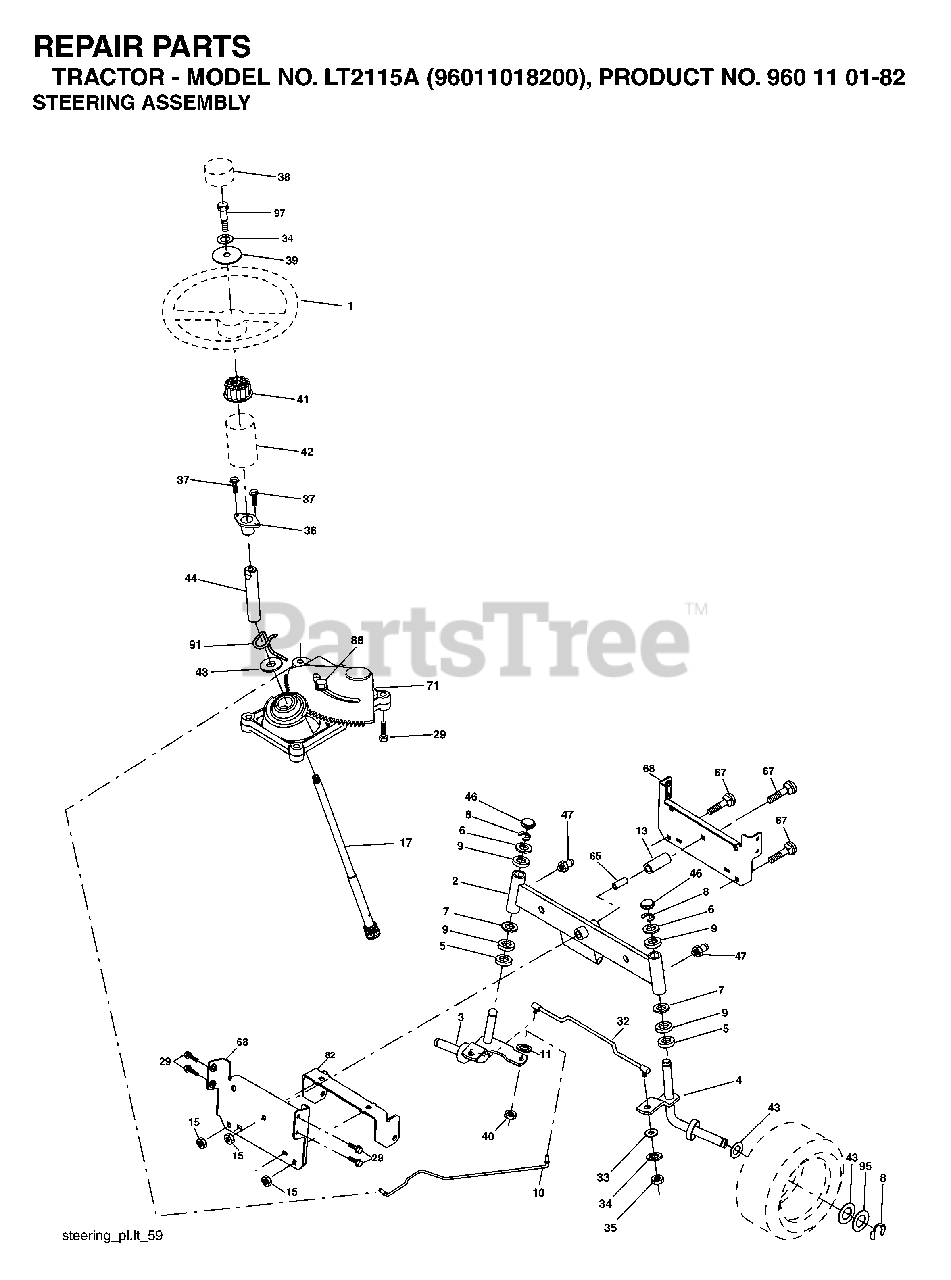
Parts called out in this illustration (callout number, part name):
1	WHEEL.STEERING.PREM.2.BLK
2	AXLE ASM.
3	SPINDLE.ASM.LH.15"TIRES
4	SPINDLE.ASM.RH.15"TIRES
8	RING CLIP
9	BRNG T
10	DRAGLINK.15".TIRES.2001
11	WASHER, LOCK 3/8
13	TUBE, PIVOT AXLE
15	NUT
17	SHAFT STEERING SPLINE
29	SCREW, 3/8-16X3/4
33	WASHER M
34	LOCKWASHER
35	NUT, CROWNLOCK
36	BUSHING, STEERING
38	INSERT.CAP.STRG.WH.BLACK
39	WASHER.11/32
40	NUT CROWNLOCK 3/8-24
41	ADAPTER, WHEEL STNG..
42	BOOT.STEERING.SHAFT.BLACK
44	SHAFT.EXTEN.STRG.SPLINE
46	CAP.SPINDLE
47	FITTING.GREASE.TAPERED
65	SPACER BRACE AXLE
67	BOLT CARRIAGE
68	BRACE.AXLE.15"TIRES
71	STEERING ASM
82	BRACKET.SUSP.CHASSIS.FRONT.15
88	BOLT, SHOULDER 7/16-20
91	CLIP.STEERING
95	WASHER.HARDENED
